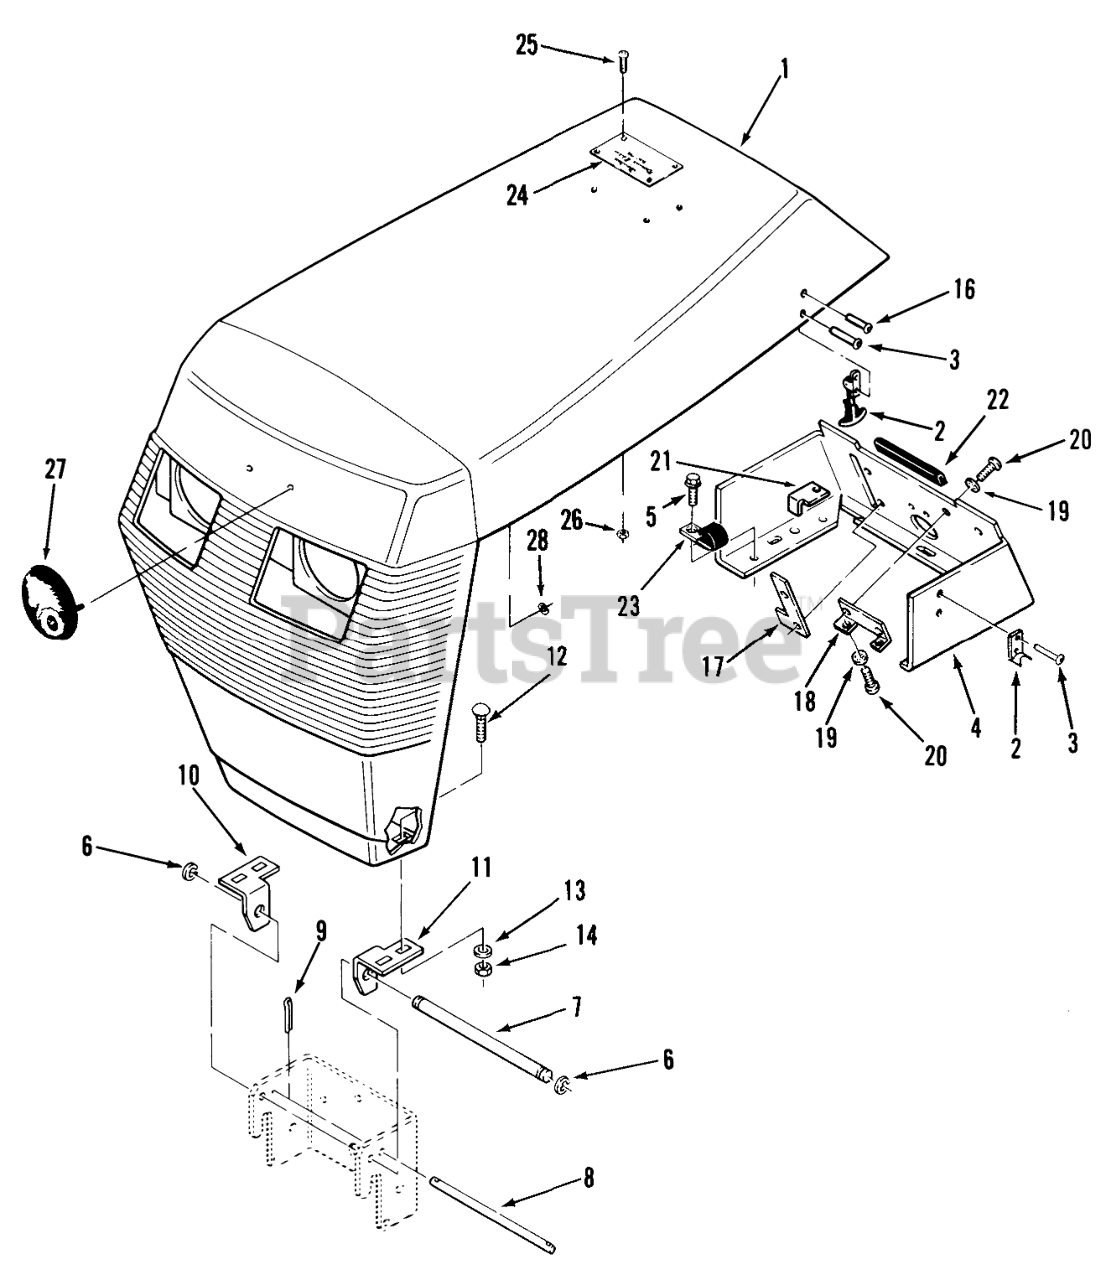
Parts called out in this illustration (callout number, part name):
1	Hood
2	Hood Latch (includes 109236 Handle Ass-y & 109237 Latch Keeper)
3	RIVET -4
4	Console
4	CONSOLE B
5	SCREW
6	RING-RETAINING
7	GRILL PIVOT ROD
8	ROD-HOOD STOP
9	Cotter Pin
10	BRKT-GRILL PIVOT R
11	BRKT-GRILL PIVOT R (NS)
12	Bolt-Carriage
14	Nut
16	RIVET
17	STOP THROTTLE
18	Bracket 211-5, YT12A Only
19	Washer-Lock
20	Screw #6-32 x 1/4 Black
21	PTO Stop
22	EDGING-CONSOLE
23	J-Clip
24	Name Plate 420-LSE Only
25	Screw #6-32 x 1/2 420-LSE Only
26	Nut #6-32 420-LSE Only
27	Front Hood Ornament 420-LSE Only
28	SPEED NUT
